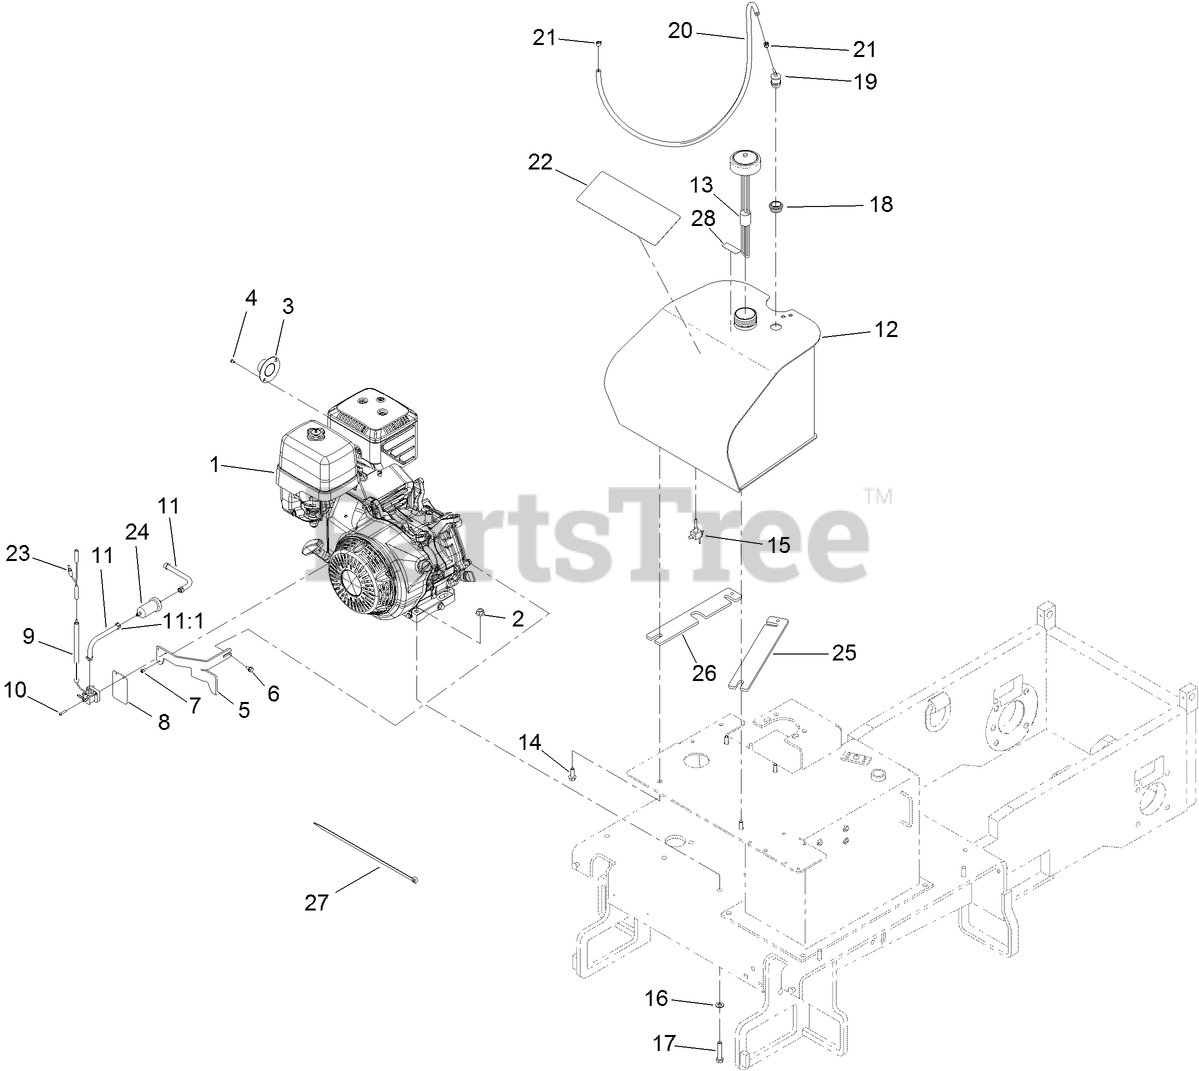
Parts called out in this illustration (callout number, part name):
1	ENGINE-HONDA, GX390
2	NUT-HF
3	DEFLECTOR-EXHAUST
4	SCREW-SELF TAPPING
5	BRACKET-SWITCH, STOP FUEL
6	SCREW-HWH
7	SCREW-HSH
8	HANG TAG-RUN, STOP
9	FUEL SHUT OFF VALVE ASM
10	SCREW-HSBH
11	FUEL HOSE KIT
11:1	CLAMP-HOSE
12	TANK ASM
13	GAUGE-FUEL
14	SCREW-HHF
15	VALVE-STRAINER
16	WASHER-FLAT
17	SCREW-HH
18	GROMMET
19	VALVE-VENT, FUEL
20	HOSE-FUEL
21	CLAMP-HOSE
22	DECAL-OPERATION
23	HARNESS-WIRE, SHUT DOWN T
24	FILTER-FUEL
25	PLATE-TANK STAND OFF
26	PLATE-TANK STAND OFF
27	TIE-PLASTIC
28	DECAL-WARNING, ETHANOL
